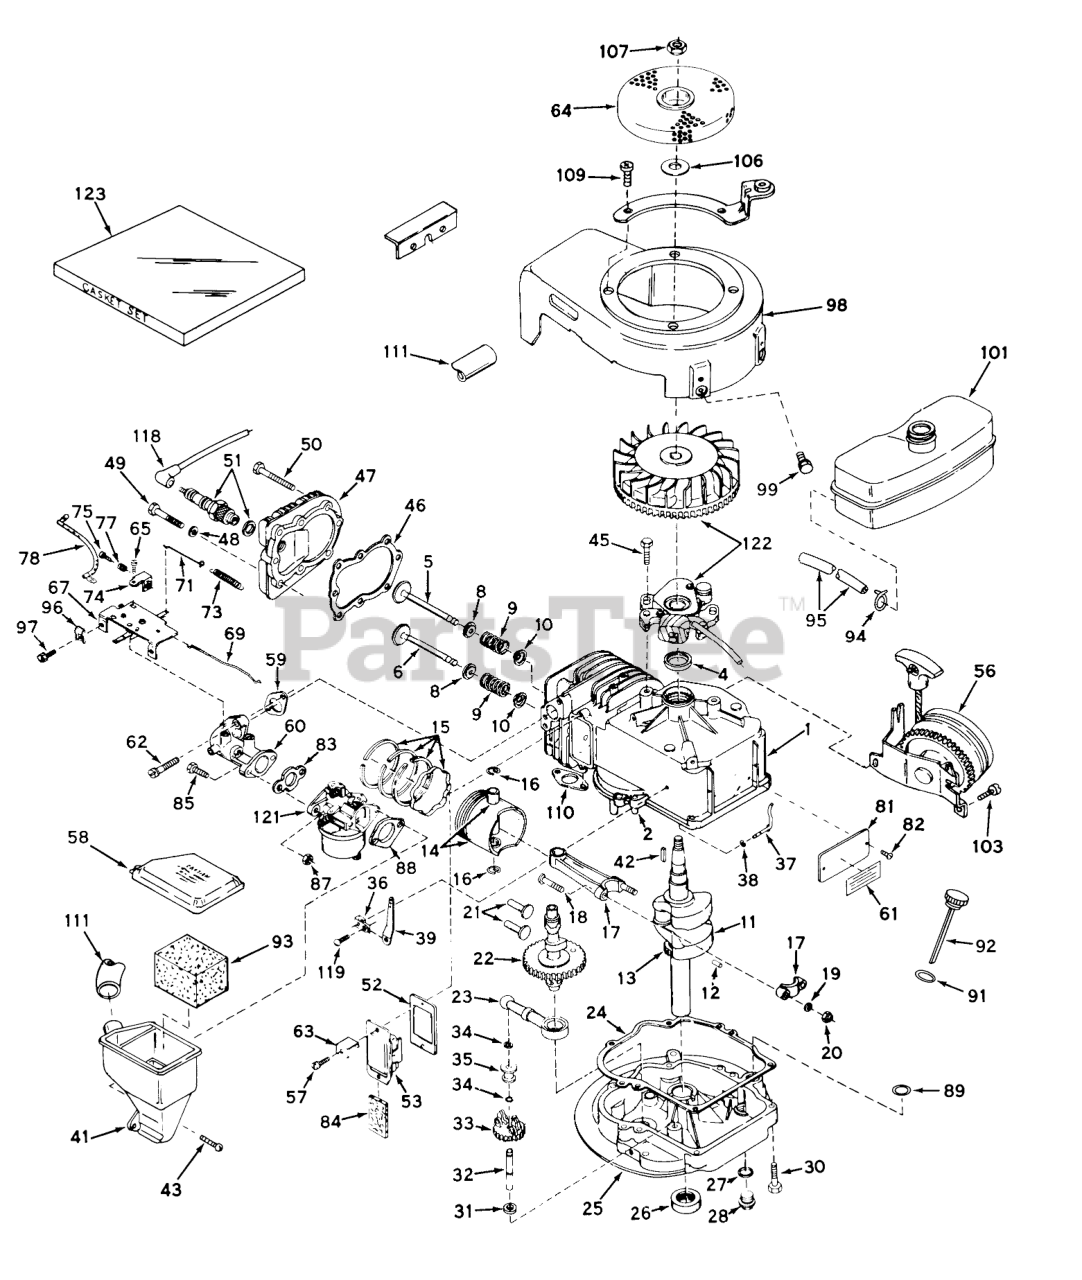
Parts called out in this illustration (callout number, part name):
1	Cylinder Assy. (Incl. Nos.2, 4 )
2	Pin, Dowel
4	OIL SEAL
5	Valve, Intake (Std.) (Incl. Nos. 8, 9 & 10)
5	Valve, Intake (1/32" over size) (Incl. Nos. 8, 9 & 10)
6	Valve, Exhaust (Std.) (Incl. Nos. 8, 9 & 10)
6	Valve, Exhaust (1/32" over size) (Incl. Nos. 8, 9, & 10)
8	Cap-Upper Valve Spring
9	Spring-Valve
10	Cap-Valve, Spring
11	Crankshaft Assy. (Incl. Nos. 12 & 13)
12	Pin, Groove
13	Gear, Crankshaft
14	Piston & Pin Assy. (Std.) (Incl. 2 of No. 16)
14	Piston & Pin Assy. (.010 oversize) (Incl. 2 of No. 16)
14	Piston & Pin Assy. (.020 oversize) (Incl. of No. 16)
15	Ring Set, Piston (Std.)
15	Ring Set, Piston (.010 o.s.)
15	Ring Set, Piston (.020 o.s.)
16	Ring-Retaining, Piston Pin
17	Rod Assy., Connecting (Incl. Nos. 18, 19 & 20)
18	Bolt, Connecting
20	LOCKNUT
21	Lifter-Valve
22	Camshaft
23	Oil Pump ASM
24	Gasket, Mounting
25	Flange Assy., Mtg. (Incl. Nos. 26, 27, 28 & 32)
26	Seal Oil
27	Gasket-Oil Drain
28	Plug Oil Drain
30	Screw (1/4-20 x 1-1/4)
31	Washer-Flat
32	Shaft-Governor
33	Governor Gear ASM
34	Ring-Retaining
35	Spool-Governor
36	Clamp-Lever, Governor
37	Rod, Governor (Incl. No. 38)
38	Washer-Flat
39	Governor Lever
41	Body, Air Cleaner
42	Key Flywheel
43	Screw, Fil. Hd. Sems
46	Gasket-Cylinder Head
47	CYLINDER HEAD
49	Screw
50	Screw Hex Hd. Cap
51	SPARK PLUG
52	Gasket Breather
53	Breather Assy. (Incl. Nos. 52 & 84)
56	Starter, Side Mount
58	Cover, Air Cleaner
59	Gasket, Intake
60	Pipe, Intake
61	480B GIL SNWTHWR O/
62	Screw, Fil. Hd. Sems
63	Retainer Clip
64	Screen, Flywheel
65	Screw (10-24 x 9/16)
67	Control Assy., Speed
69	Link Governor
71	Link-Governor
73	Spring, Governor
74	Brachet, Control
75	Screw, Hex Hd.
78	Wire, Ground
81	IDENTIFICATION PLATE
83	Gasket
84	Element-Breather
85	Screw (1/4-28 x 7/8)
87	Nut and Lock Washer (1/4-28)
88	Gasket-Air Cleaner
92	Dipstick, Oil
93	Element, Air Cleaner
94	Clamp-Line, Fuel
95	Line-Fuel (8.62)
96	Conduit
97	Screw (10-32 x 3/8)
98	Housing, Blower
99	Screw (1/4-20x19/32)
101	Tank, Fuel
103	Screw
106	Washer
107	Hex Nut
110	Gasket Exhaust
111	Tube, Air Cleaner
118	Cover-Spark Plug
119	Screw
121	Carburetor
122	Magneto
123	Gasket Set
